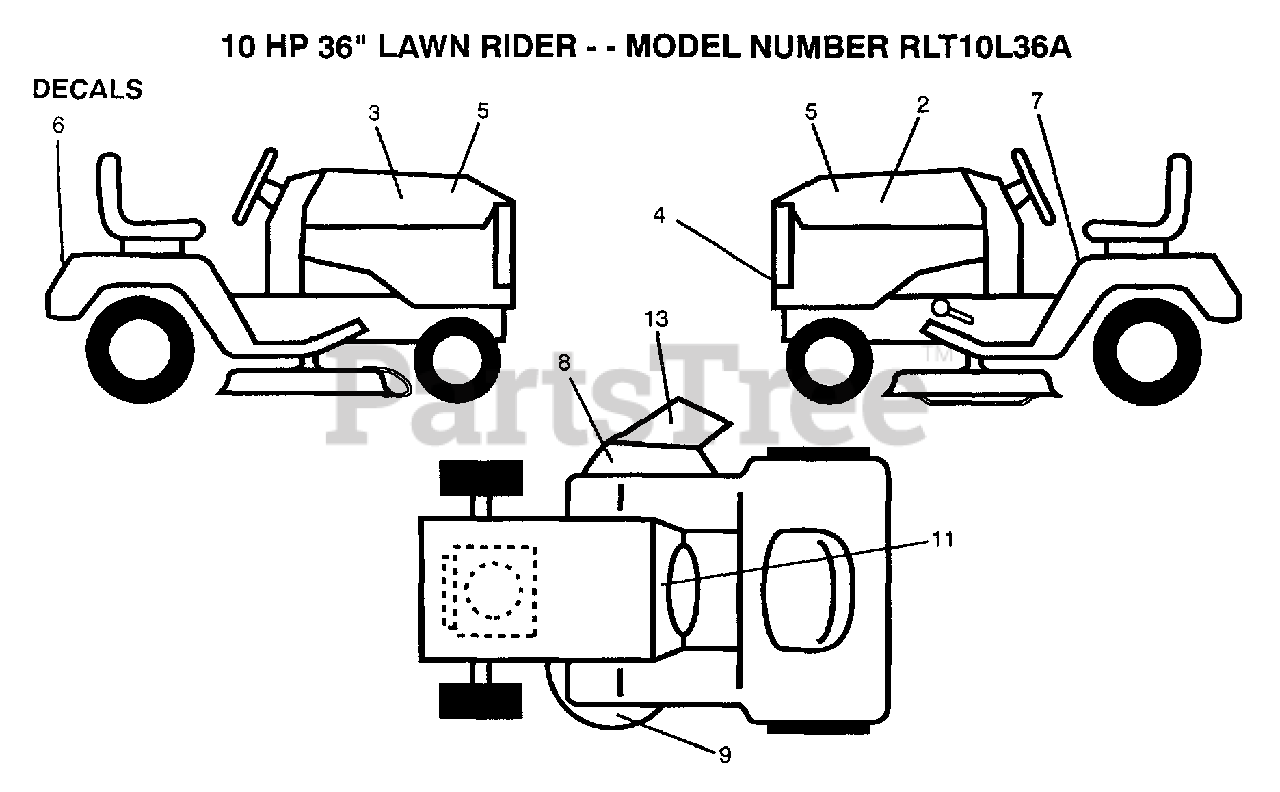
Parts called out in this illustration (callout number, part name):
2	"DECAL,STP HD LH"
3	"DECAL,STP HD RH"
4	GRILL DECAL
5	DECAL, HP HOOD
6	FENDER DECAL
7	DECAL CAUTION
8	DECAL WARNING
9	DECAL YT
13	DECAL WARNING
